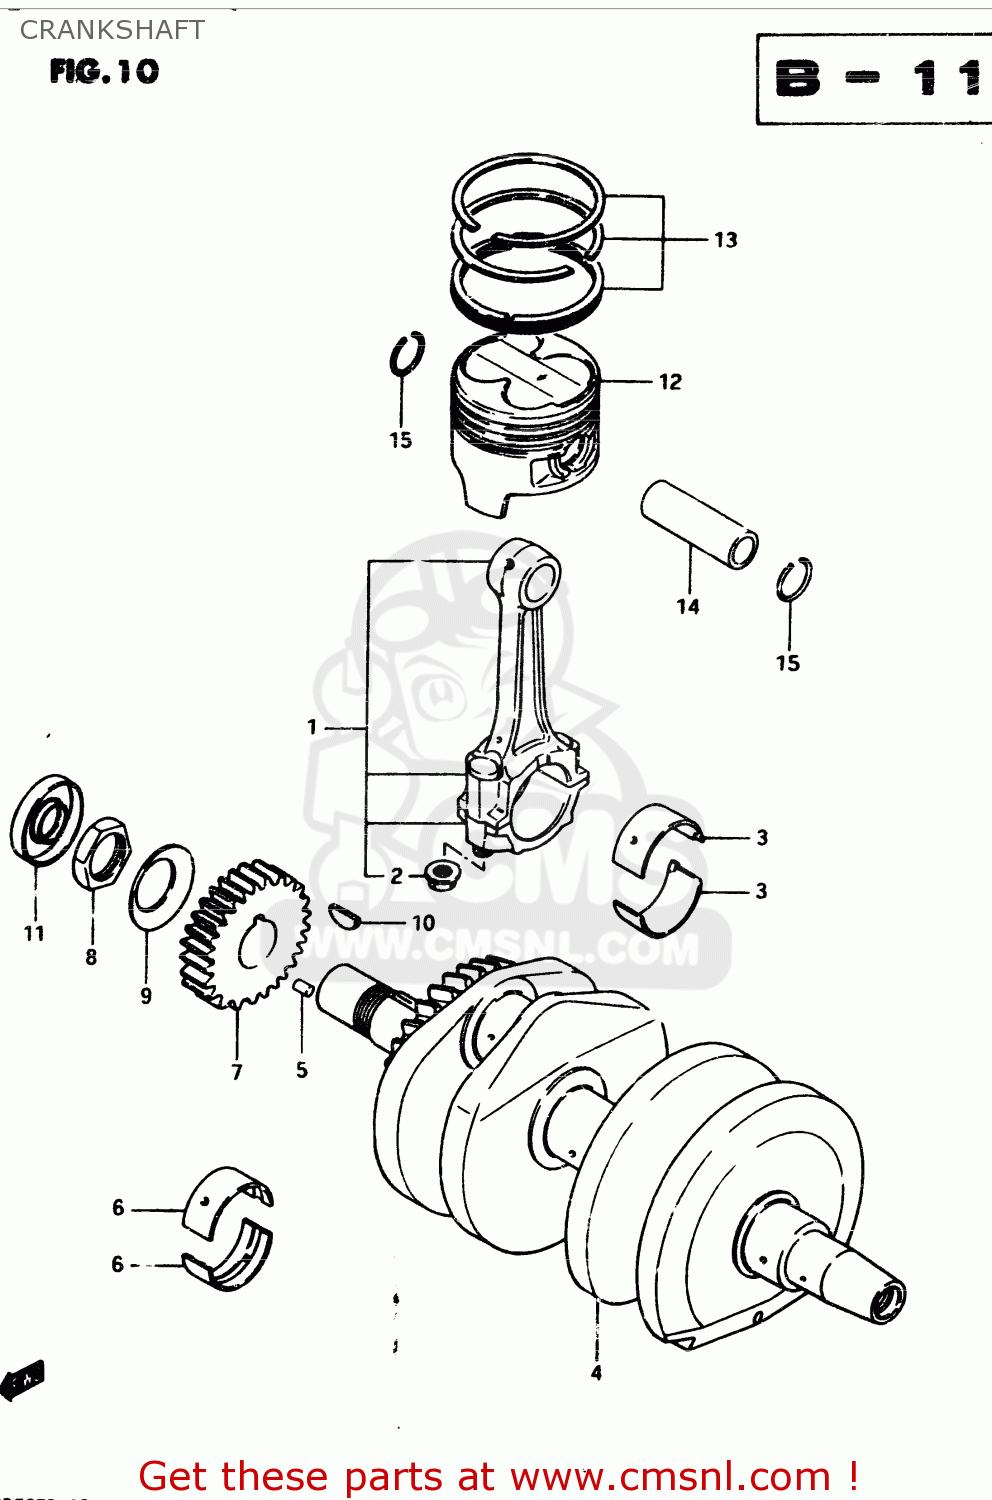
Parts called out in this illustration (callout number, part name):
1	ROD ASSEMBLY,CONNECTING
2	NUT
3	BEARING,CRANK PIN
4	CRANKSHAFT ASSEMBLY
5	PIN 3X5
6	METAL CRANKSHAFT
7	GEAR,PRIMARY DRIVE
8	NUT
9	WASHER
10	KEY
11	OIL SEAL
12	PISTON (OS:0.5)
13	RING SET,PISTON
14	PIN,PISTON
15	CIRCLIP
